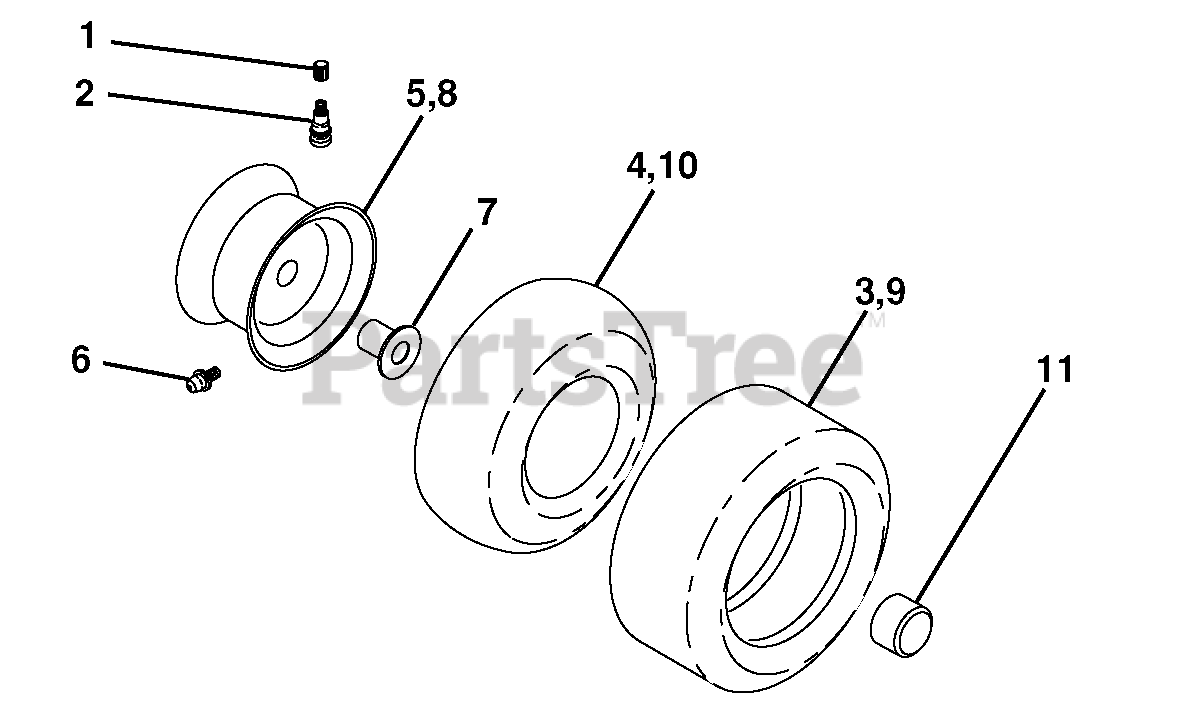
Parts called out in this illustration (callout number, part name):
1	Cap Valve Tire
2	Stem Valve
3	Tire F T 15 x 6 0 - 6
4	Tube Front
5	Rim Asm 6" Front
6	Fitting Grease
7	Bearing Flange
8	Rim Asm 8" Rear
9	Tire R T 18 x 9.5-8 Turf Saver
9	Tire R T 18 x 9.5-8 Turf Saver LT
10	Tube Rear
11	Cap Axle Blk 1 50 x 1 00
11	Sealant, Tire (10 oz. Tube)
